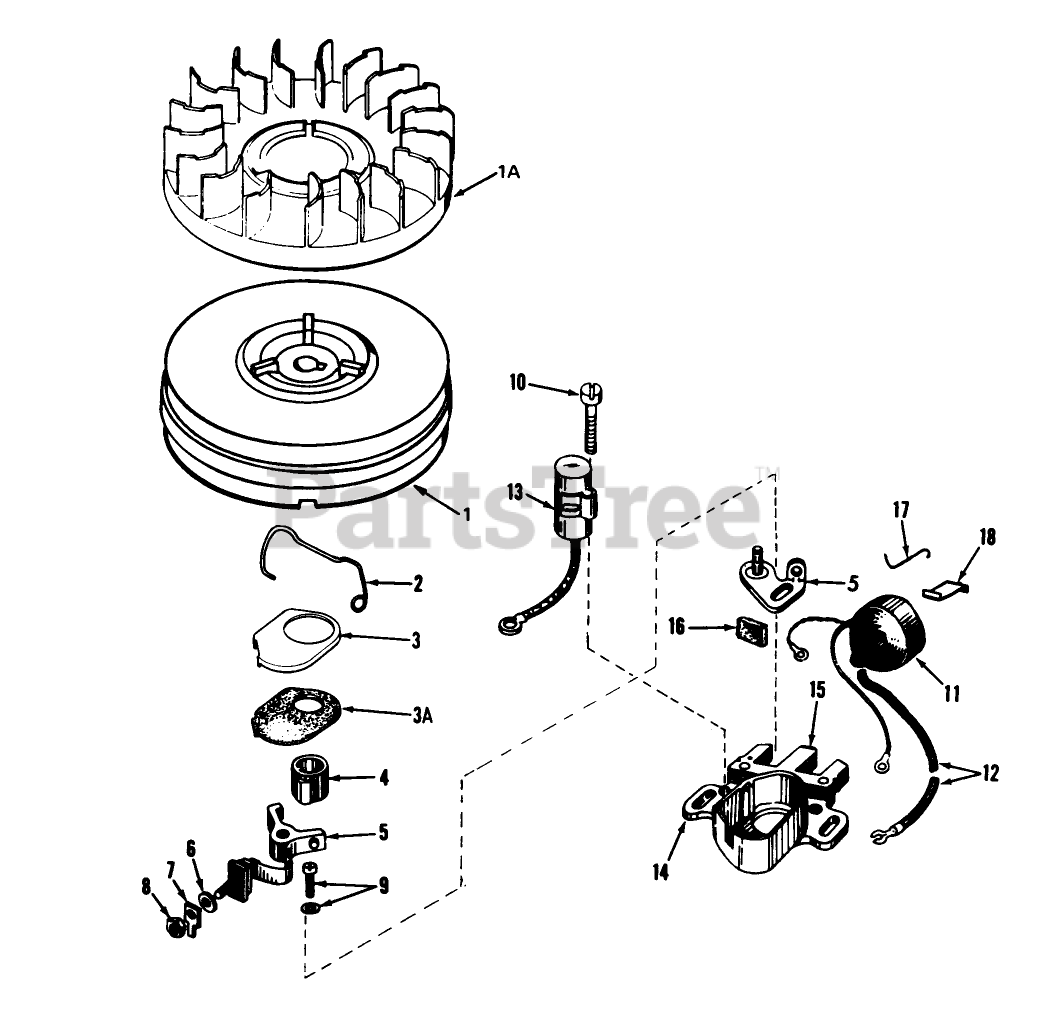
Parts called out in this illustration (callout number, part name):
1	Flywheel (Incl.Nos.1A, 3 3A)
2	Spring Breaker Box
3	Cover-Dust
3A	Gasket, Dust Cover
4	Cam, Breaker
5	Breaker Assy.
6	Washer
7	Terminal, Ground
8	DECAL
9	Breaker Screw
10	Condenser Screw
11	Coil Assy. (Incl. No. 12)
12	Wire, Lead
13	Condenser
14	Core Plate
15	Stator Assy. (Incl. Ref. #2 thru 11, 13, 14, 16, 17 19)
16	Felt,Cam Wiper
17	Clip, Coil
18	Spring Coil Wedge
